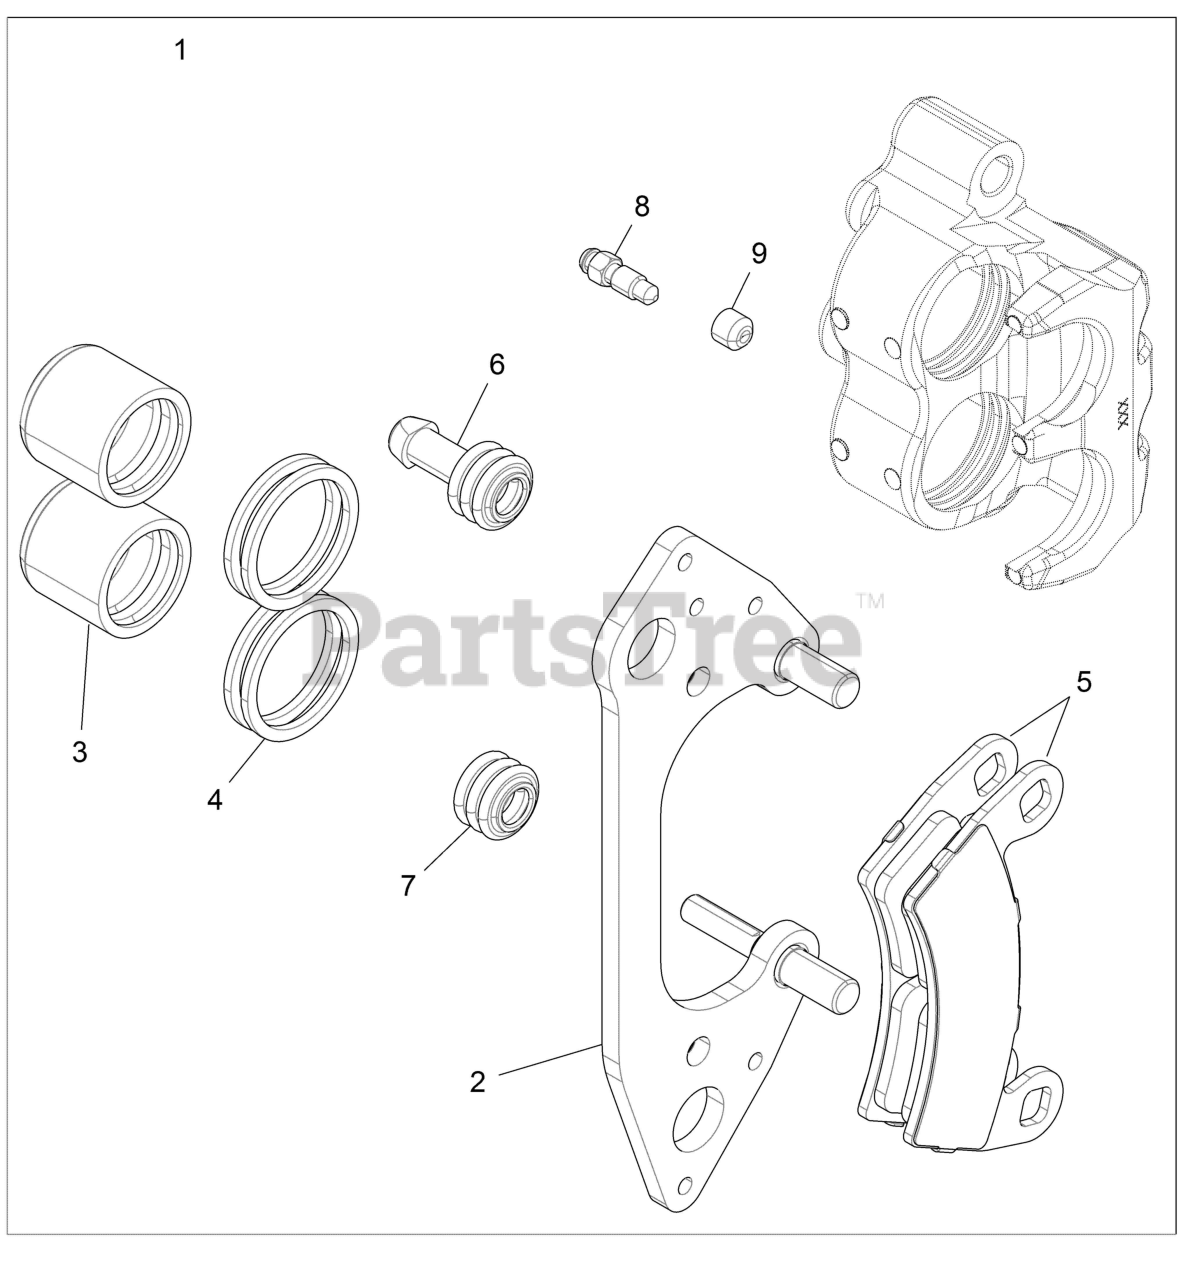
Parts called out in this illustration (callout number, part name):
1	ASM-BRK-CAL-L-DB1-3/8-GROOVED
1	ASM-BRK-CAL-R-DB1-3/8-GROOVED
2	ASM., CALIPER, MOUNT, FRONT
3	PISTON-BRAKE,1.375,AL,GROOVED
4	SEAL-CALIPER,INNER,1.375"
5	KIT-ASM,PAD,BRAKE,DB,1.375
6	BOOT-PIN BUSHING
7	BOOT-PIN SEAL
8	SCR-M7X1.0,BLEEDER,OLIVE D
9	SCR-M10X1.0X8,SOC SET-OD
